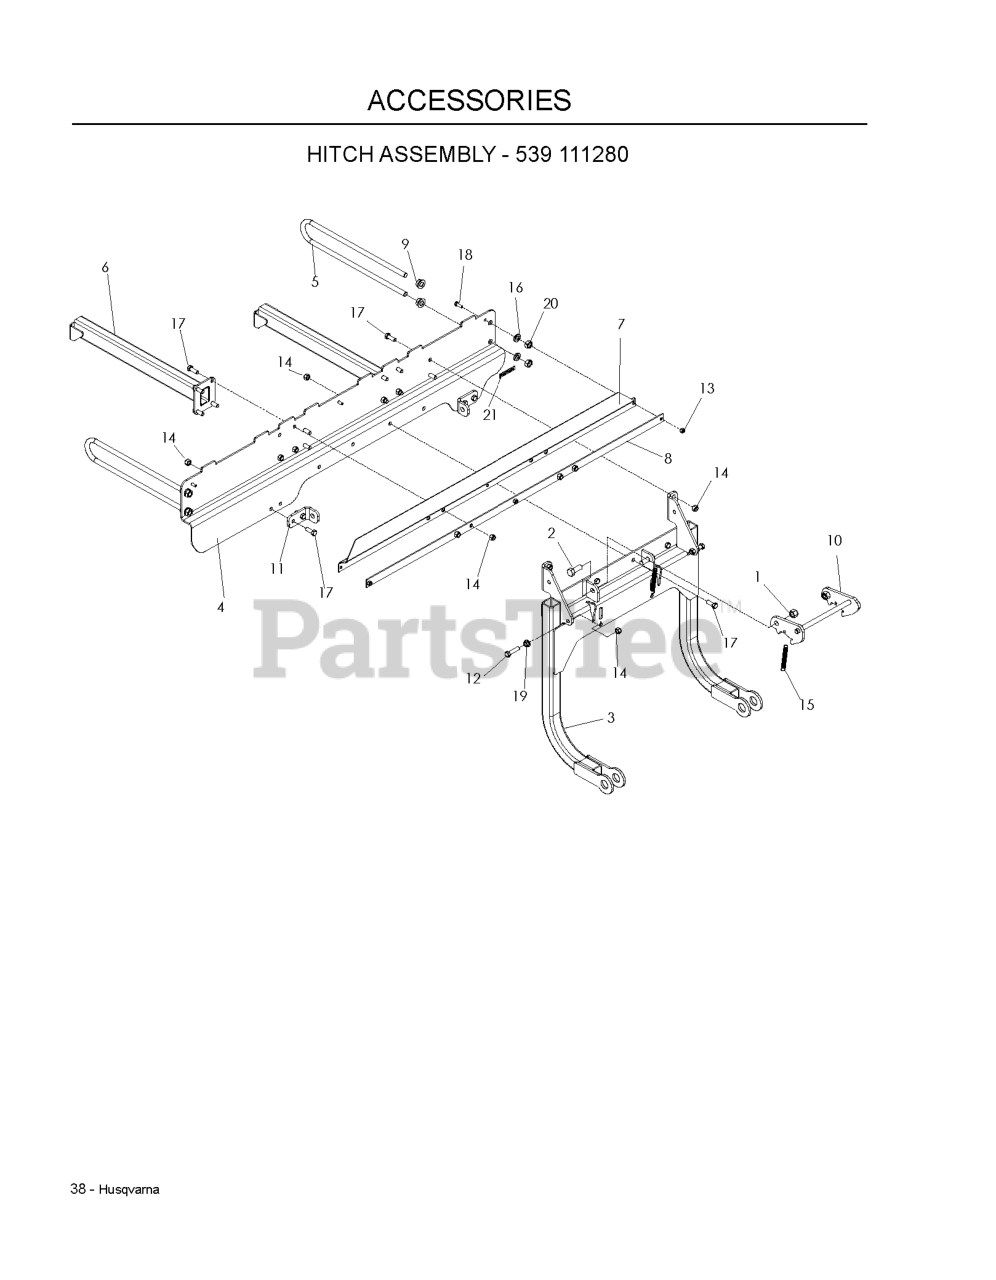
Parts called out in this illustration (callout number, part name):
1	NUT 1/2-13 HEX NYLOC ZD
2	HCS 1/2-13 X 1-1/4
3	HITCH WELDMENT
4	MOUNT Z BRACE
5	SUPPORT, OUTER
6	SUPPORT ARM WELDMENT
7	SEAL, RUBBER
8	SEAL STRAP
9	NUT 1/2-13 HEX
10	LATCH WELDMENT
11	BRACKET, SUPPORT
12	HCS 3/8C X 1 1/2
13	NUT.1/4-20.HEX.NYLOC.ZD
14	NUT 3/8-16 NYLOC
16	WASHER 1/2" SPLIT LOCK
17	HCS 3/8-16X1.GRD.5.ZD
18	HCS 1/4C X 3/4 HCS
19	NUT 3/8C WHIZ
20	NUT 1/2 HEX JAM
21	DECAL - PATENT PENDING
